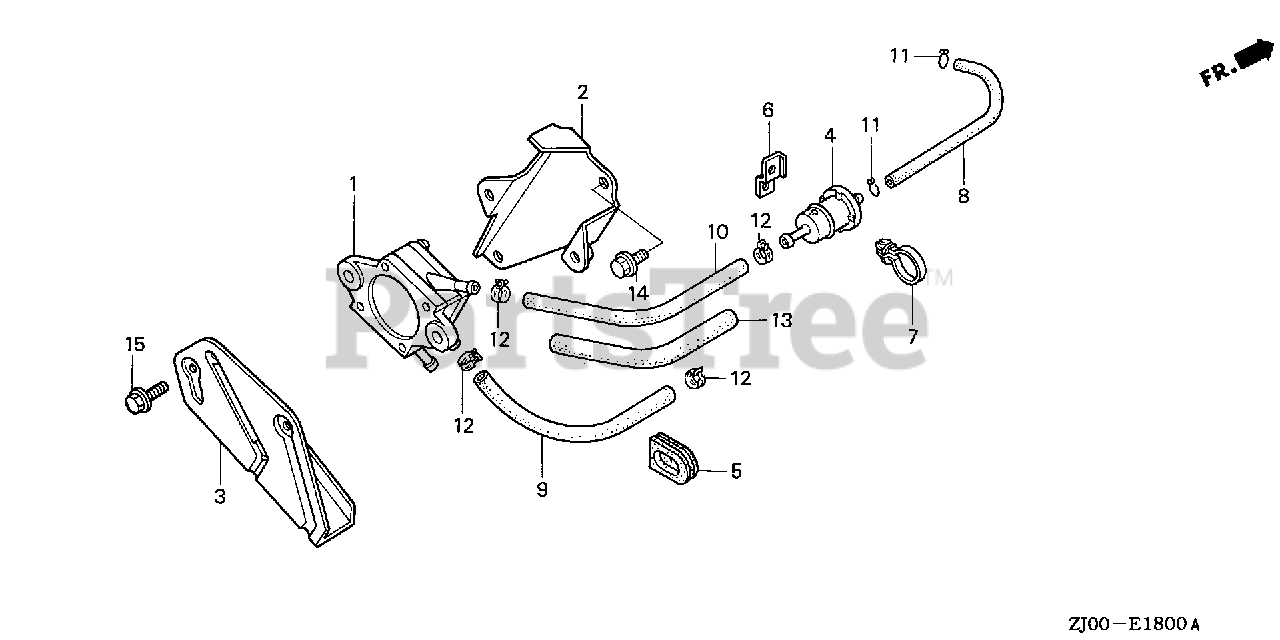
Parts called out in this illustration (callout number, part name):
1	PUMP ASSY., FUEL (MSDS)
2	STAY, FUEL PUMP (NOT AVAILABLE)
4	STRAINER, FUEL
6	BASE, CLIP
7	CLIP, WIRE HARNESS
8	BULK HOSE, FUEL (4.5X3000) (4.5X110)
9	BULK HOSE, FUEL (5.5X3000) (5.3X195)
10	BULK HOSE, FUEL (5.5X3000) (5.5X215)
11	CLIP, TUBE (B8)
12	CLAMP, TUBE (D10.5)
13	BULK HOSE, VINYL (11X13X3000) (11X13X160)
14	BOLT, FLANGE (6X8)
15	BOLT, FLANGE (6X14)
